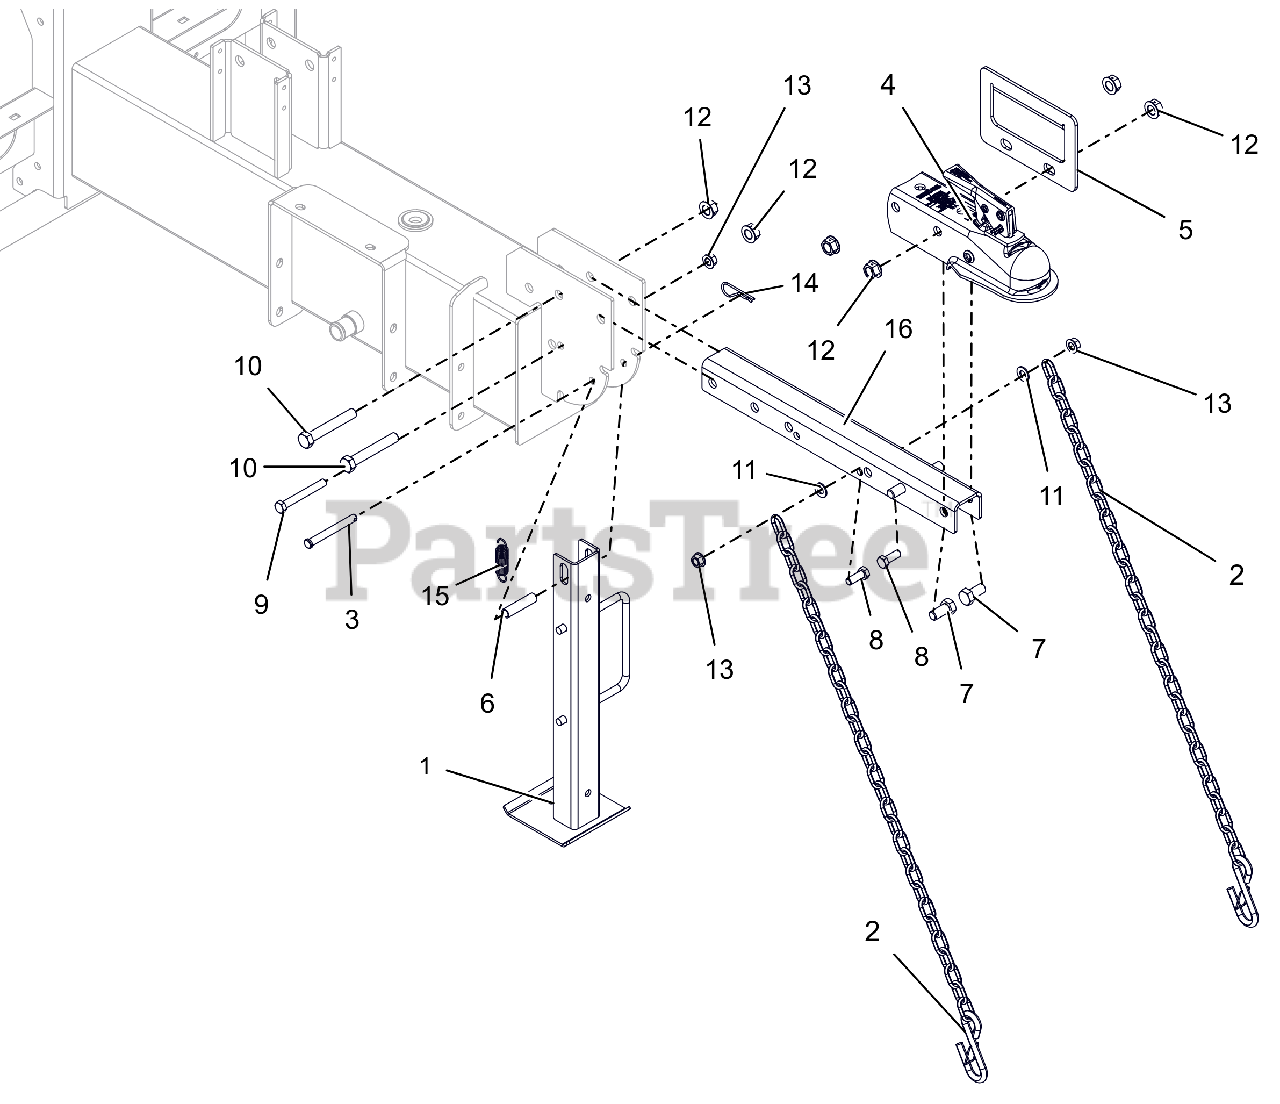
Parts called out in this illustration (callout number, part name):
1	WLDMT, JACK STAND
2	CHAIN, SAFETY 3/16"-30LINK
3	PIN-CLEV .371X3.25 YWZC
4	COUPLER-BALL 2.000"
5	HANDLE, SPLITTER DRAW BAR
6	SPCR, WHEEL .385X.500X2.00
7	@BLT-HEX .50-13X1.00 GR5 YWZC
8	@BLT-HEX .38-16X1.00 GR5 YWZC
9	@BLT-HEX .38-16X3.00 GR5 YWZC
10	@BLT-HEX .50-13X3.25 GR5 YWZC
11	@WSHR-FL-STL.406X.812X.065 YWZ
12	NUT-LK-CTR-FLG .50-13 YWZC
13	@NUT-LK-TOP-FLG .38-16 YWZC
14	HAIRPIN, #7 CLIP .094X2.31 YWZ
15	SPRG, TENSION .063X.625X2.50
16	HITCH BAR W/SAFETY DECAL
